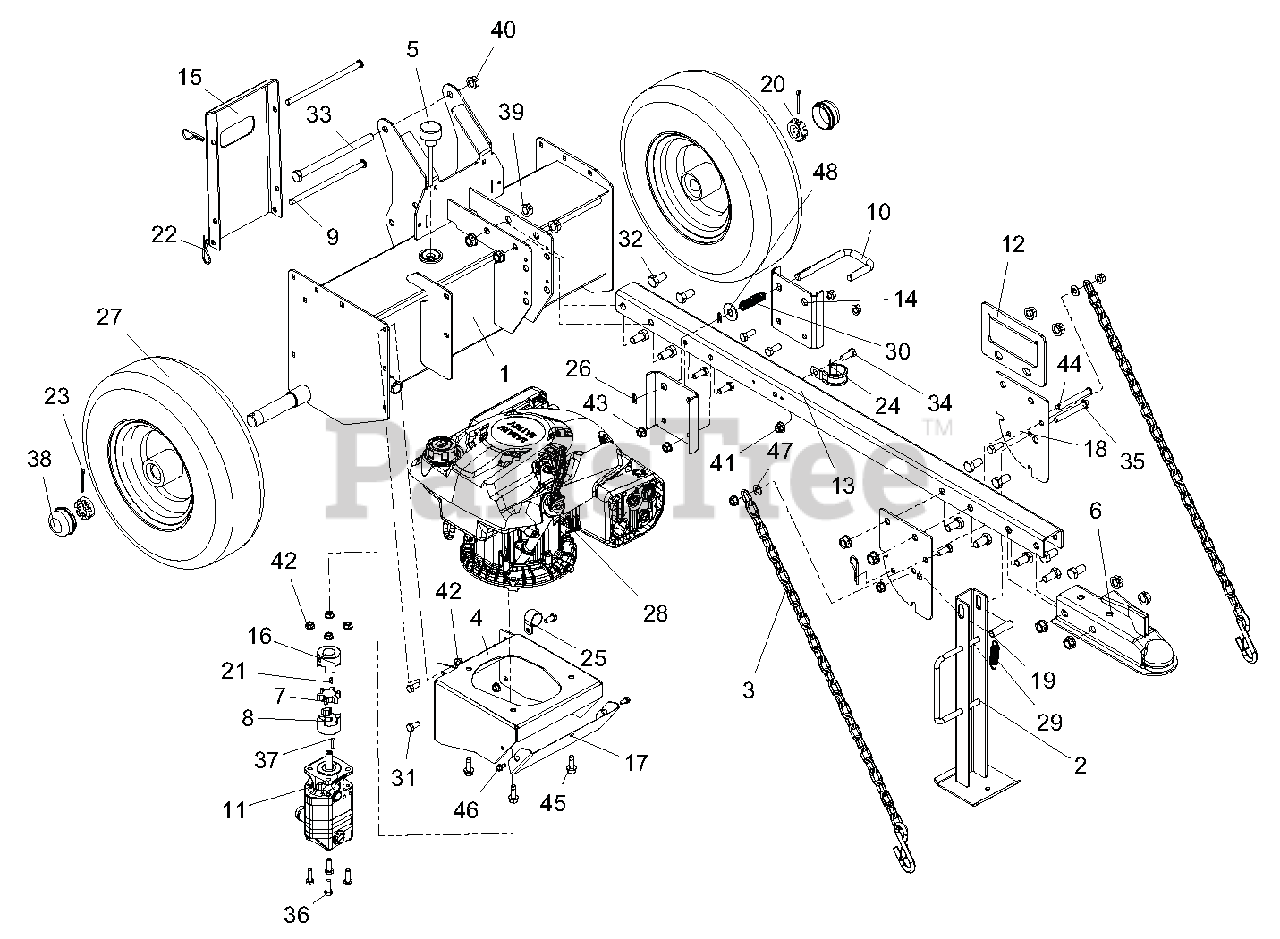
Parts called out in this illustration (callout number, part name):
1	WMT,SMALL CHASSIS
2	WLDMT, JACK STAND
3	CHAIN, SAFETY 3/16"-30LINK
4	WLDMT,ENGINE/PUMP
5	BREATHER, DIPSTICK
6	HITCH, BALL-2"
7	SPIDER,URETHANE
8	HUB,DRIVE COUPLING 1/2"
9	PIN, LOCK
10	LOCK, BEAM
11	PUMP,SPLITTER-11 GPM
12	HANDLE, SPLITTER DRAW BAR
13	BAR, DRAW
14	GUIDE, LOCK DOWN
15	SUPPORT, REAR LEG
16	HUB, DRIVE COUPLING 7/8"
17	COVER, COUPLING
18	MOUNT, SPRING LOADED JACK
19	SPCR, WHEEL .385X.500X2.00
20	NUT-SL 1.0-14
21	KEY-WDRF .125X.50X.20 (HRDEND)
22	HAIRPIN, #7 CLIP .094X2.31 YWZ
23	@PIN-CTR .15X1.50 YWZC
24	CLAMP, CUSHIONED STEEL 1.25
25	CLAMP, COUSHIONED STEEL REV
26	CLIP, SPRING
27	WHEEL, SPLITTER
28	ENGINE, SUBARU EA175V
29	SPRG, TENSION .063X.625X2.50
30	SPRG, COMP .058X.65X2.13 WLD15
31	@BLT-HEX .31-18X.75 GR5 YWZC
32	@BLT-HEX .50-13X1.00 GR5 YWZC
33	@BLT-HEX .50-13X7.50 GR5 YWZC
34	@BLT-HEX .38-16X1.00 GR5 YWZC
35	@BLT-HEX .38-16X3.00 GR5 YWZC
36	@BLT-HEX .31-18X1.00 GR5 YWZC
37	KEY-SQ .188X.75X.188
38	CAP, DUST
39	NUT-LK-CTR-FLG .50-13 YWZC
40	NUT-LK-CTR-FLG .50-13 YWZC
41	@NUT-LK-NYL-FLG .38-16 YWZC
42	@NUT-LK-TOP-FLG .31-18 YWZC
43	@NUT-LK-TOP-FLG .38-16 YWZC
44	PIN-CLEV .371X3.25 YWZC
45	@SCR-TAP .38-16X1.00 HWH TR YZ
46	SCR-TAP .25-20X.50 HWH TR YWZ
47	@WSHR-FL-STL.406X.812X.065 YWZ
48	@WSHR-FL-STL.563X1.38X.109YWZC
